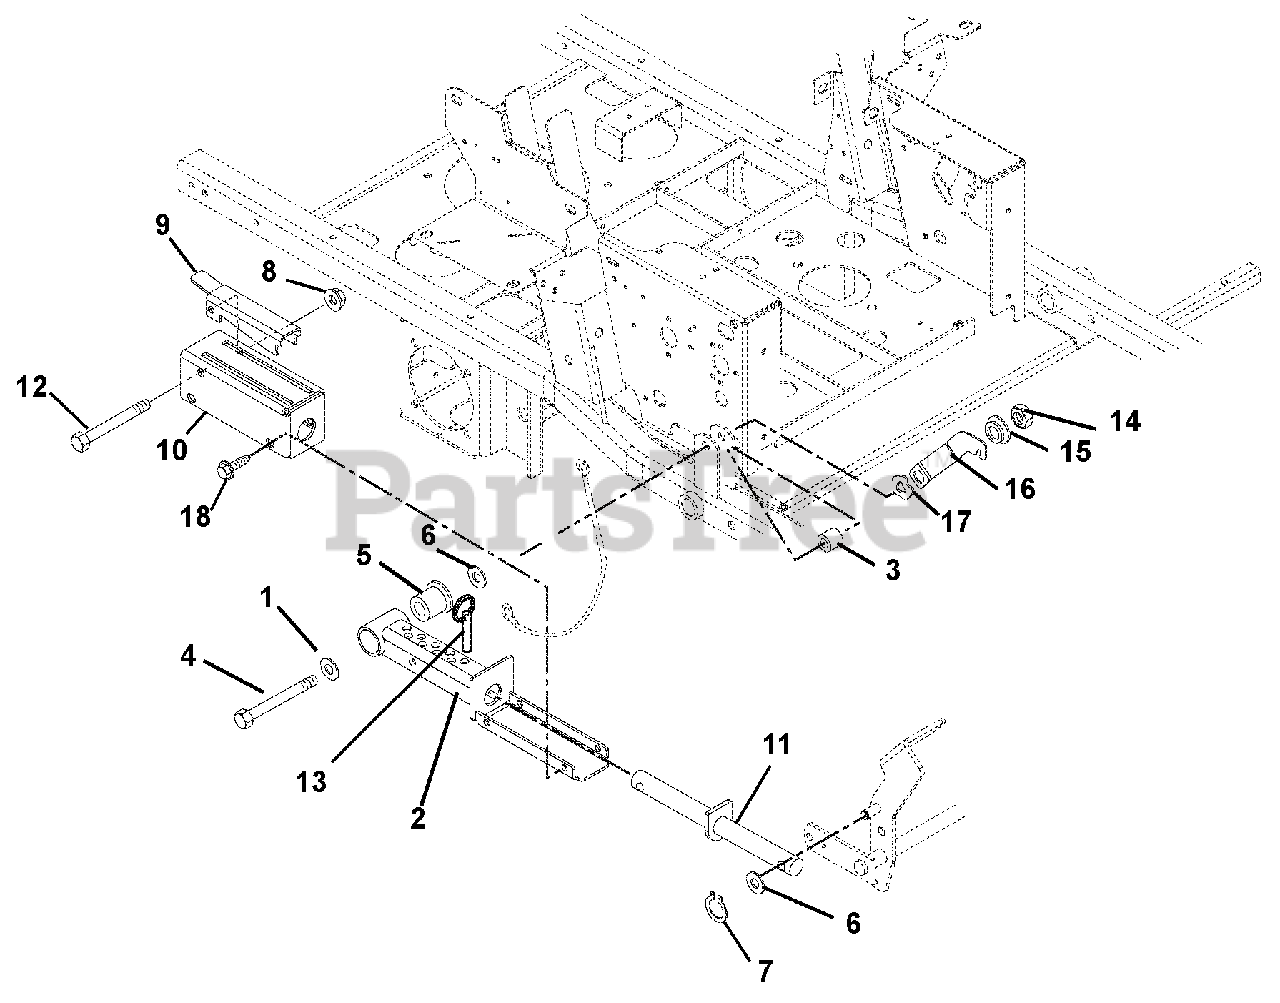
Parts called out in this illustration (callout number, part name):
1	Washer, Flat Steel .531 x 1.250 x .10
2	Weldment, Mechanical Lift
3	Bushing .516 x 1.00 x 1.05
4	Bolt, Hex .50-13 x 5.00 Grade 5
5	Bearing, Pedestal Powdered Metal
6	Washer, Flat Steel .656 x 1.310 x .095
7	Ring, Retaining External .625 x .050
8	Nut, Locking Top Flange .38-16
9	Lock-Up, Mechanical Lift
10	Weldment, Mechanical Lift Cover
11	Weldment, Mechanical Lift Shaft
12	Bolt, Hex .38-16 x 3.25 Grade 5
13	Pin, Spring Ball .375 O.D. x 1.50
14	Nut, Locking Top Flange .50-13
15	Bushing, Flange .515 x .75 x .275 x 1.12
16	Latch, Footboard
17	Washer, Wave .076 x 1.12 x .08
18	Screw, Tapping .38-16 x .50
